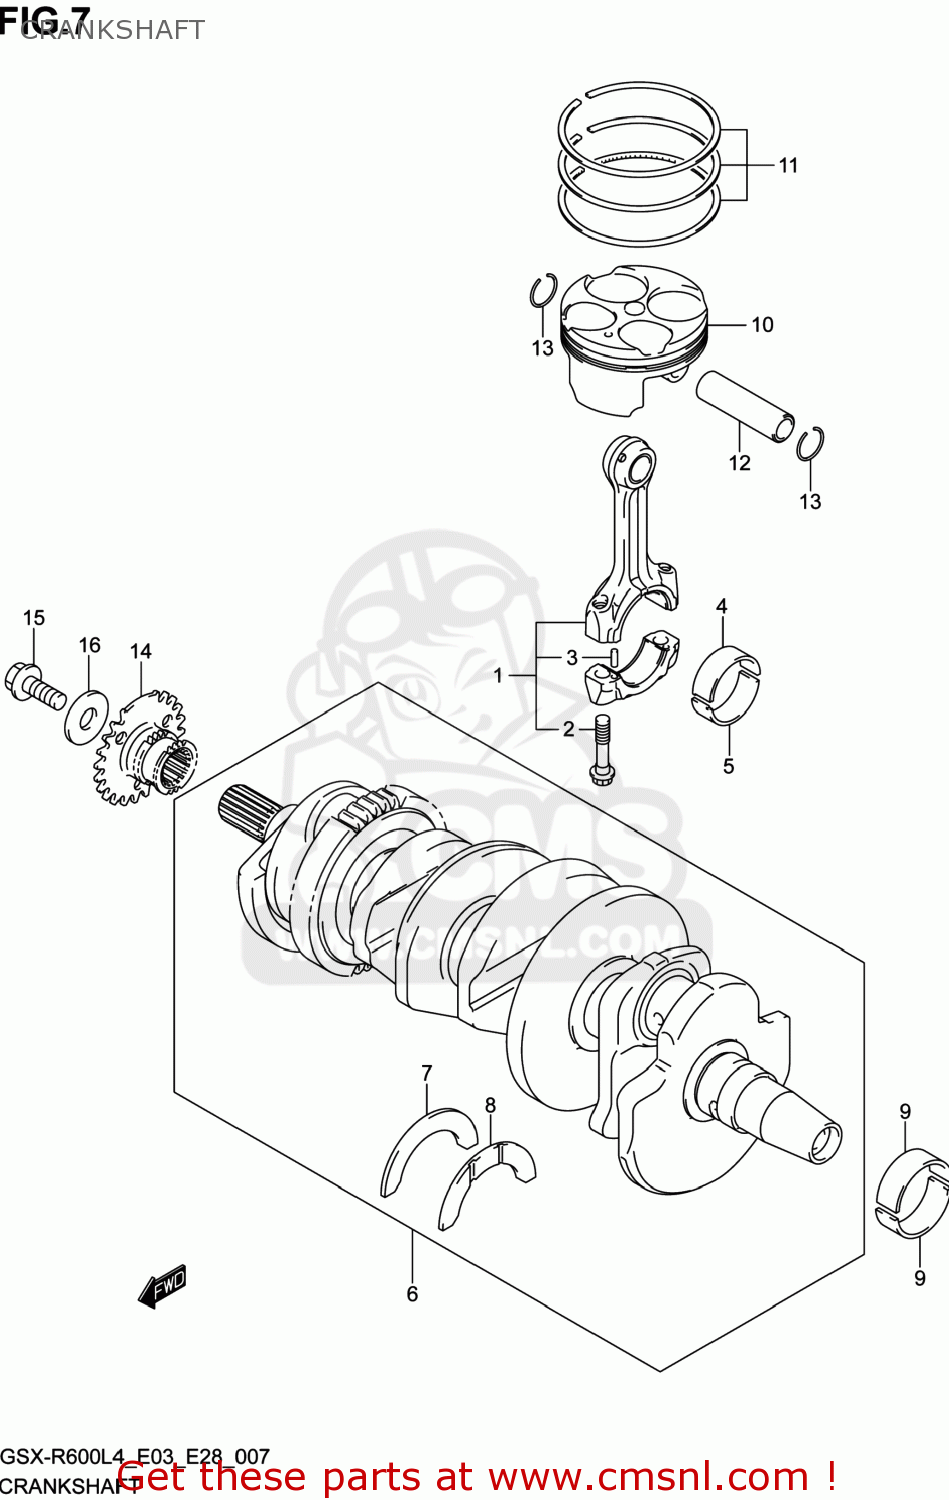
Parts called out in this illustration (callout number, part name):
1	CONNECTING ROD ASSY
2	BOLT,CONNECTING ROD
3	PIN
4	BEARING,CRANK PIN
5	BEARING,CRANK PIN
6	CRANKSHAFT SET
7	BEARING,CRANK THRUST(GREEN)
8	BEARING,CRANK THRUST(RED)
9	BEARING,CRANKSHAFT
10	PISTON
11	RING SET,PISTON
12	PIN,PISTON
13	RING,SNAP 14MM
14	SPROCKET,CAM CHAIN DRIVE
15	BOLT(10X23)
16	WASHER
